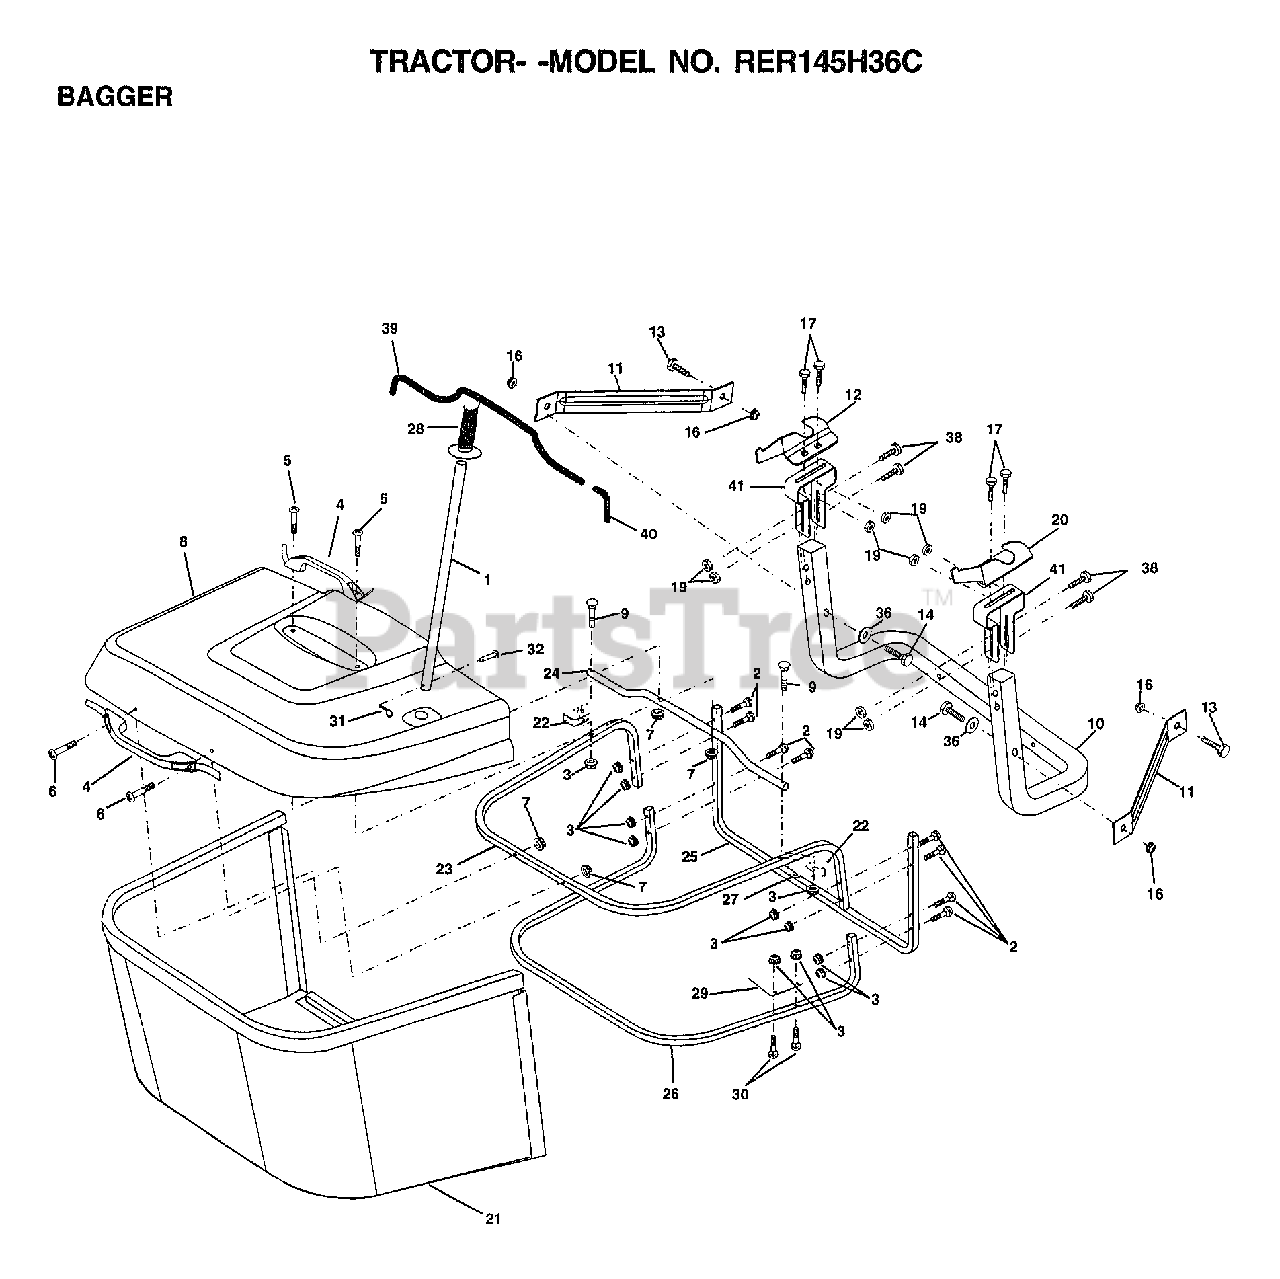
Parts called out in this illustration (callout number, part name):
1	TUBE HANDLE BAGGER
2	BOLT.CARRIAGE.1/4-20X2.0
4	HANDLE BAGGER
5	"SCREW,PAN.HEAD"
7	NUT.WIZ.LOCK
9	BOLT CARRIAGE
10	TUBE SUPPORT BAGGER CRD
11	BRKT.SUPT.UPPER.BAG.CRD
12	BRACKET HORIZ ADJ BGGR LH CRD
13	BOLT
14	BOLT.HEX.3/8-16X2-1/2
17	BOLT
18	WASHER M
19	"NUT HEX,LOCK,FLAN"
20	BRACKET HORIZ ADJ BGGR RH CRD
21	BAG.ASM.CRD
22	BRKT.SIDE.BAG.CRD
23	TUBE.UPPER.BAG.CRD
24	TUBE.PIVOT.BAG.CRD
25	TUBE.FT.BAG.CRD
26	TUBE.LOWER.BAG.CRD.
27	BUSHING SNAP BAGGER CRD
28	GRIP
31	RETAINER M
32	RIVET.DRILL.1.75
38	BOLT.5/16-18X2.5
41	BRACKET VERT ADJ BAGGER CRD
42	NUT
